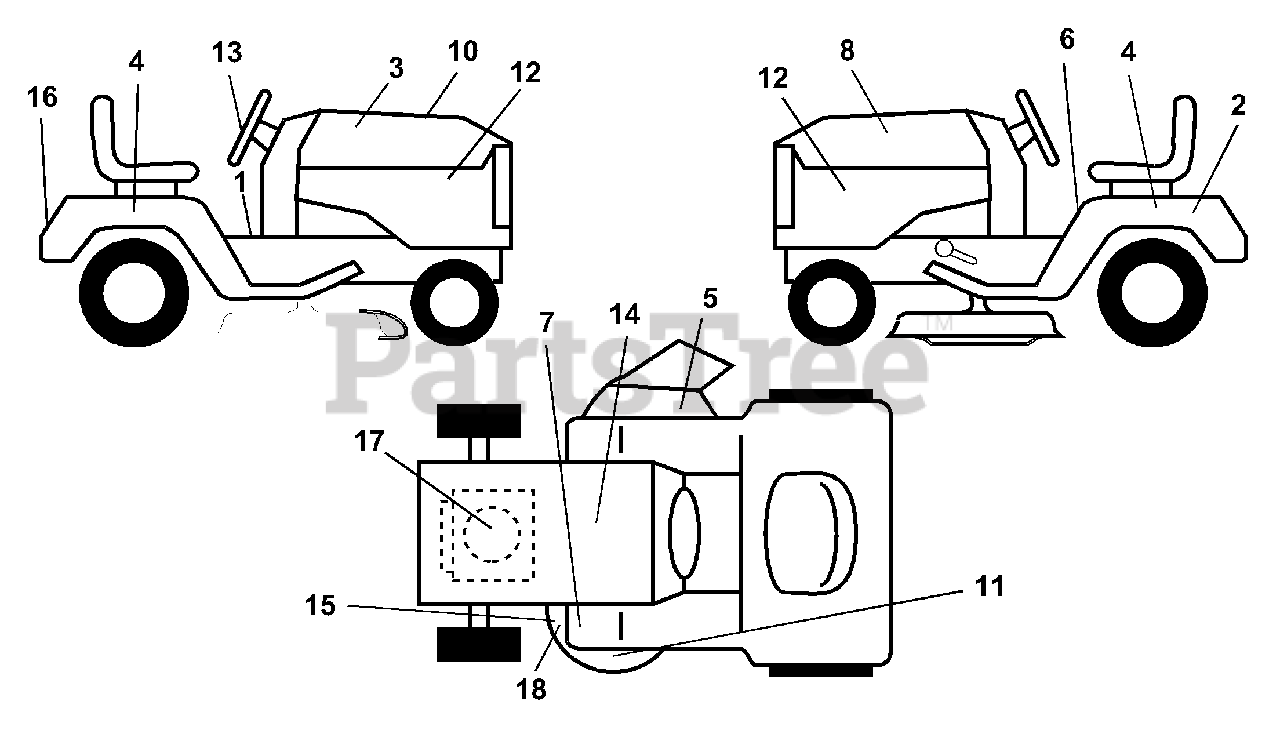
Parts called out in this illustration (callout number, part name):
1	Decal Instruction Saddle Oper.
2	Decal Battery
3	Decal Hood RH
4	Decal Fender Auto
5	Decal Warning
6	Decal Danger Fender Eng
7	Decal Clutch/brake Eng
8	Decal Hood LH
10	Decal Hood Replace Parts
11	Decal Deck Mw/Ven
12	Decal Side Panel
13	Decal Insert Strg
14	Decal Bat Dan/Poi P/L Symbols
15	Decal V-Belt Sch
16	Decal Logo Fender
17	Decal HP Engine
18	Decal V-Belt Drive Sch
